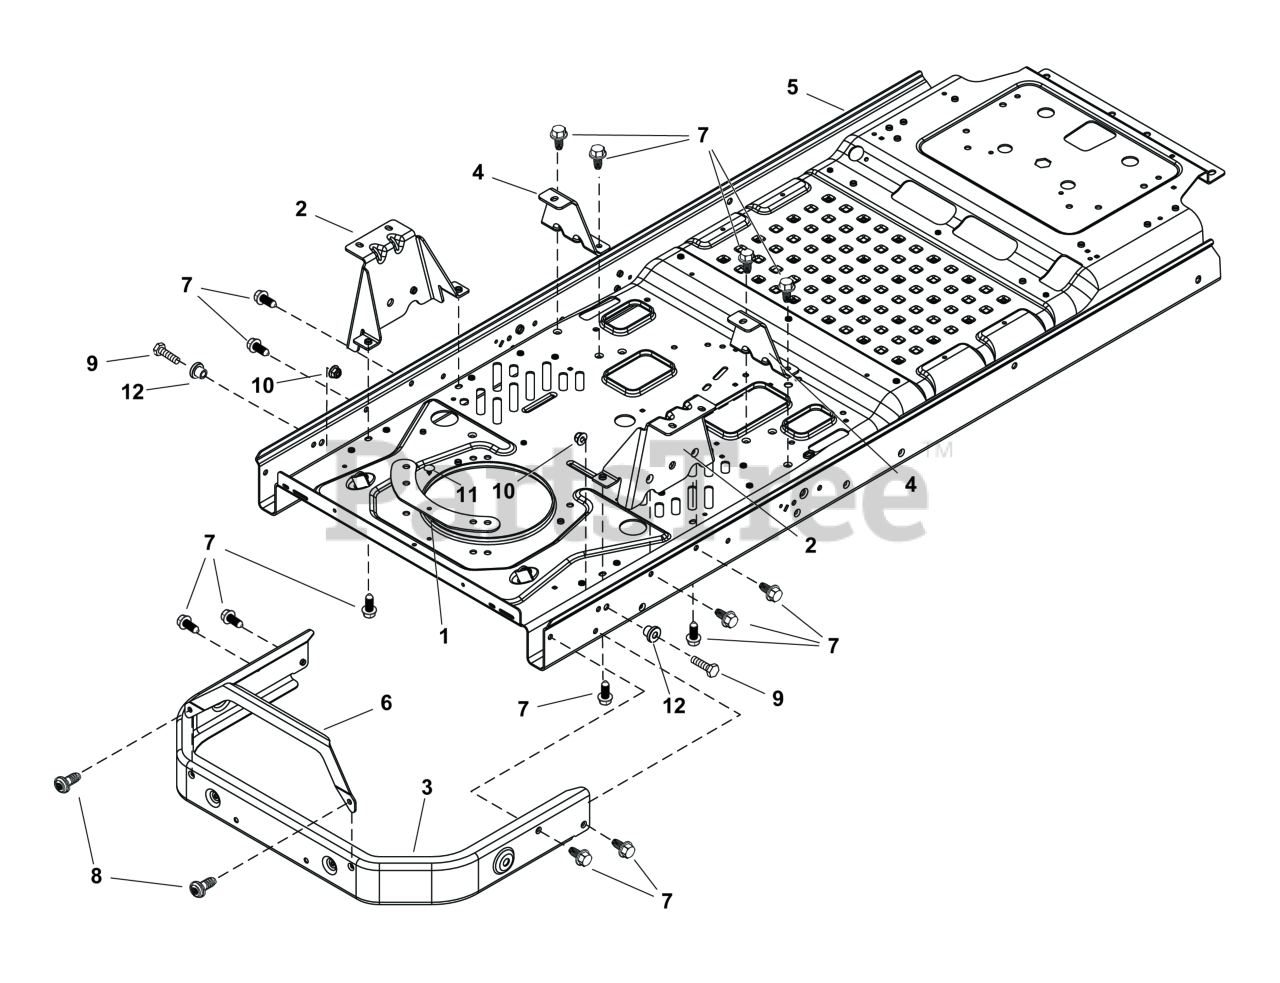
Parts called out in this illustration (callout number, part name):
1	PLATE, Retainer
2	BRACKET, Transmission Mounting (RH)
3	BUMPER, Bumper
4	BRACKET, Transmission Mounting (LH)
6	BRACKET, Rear Muffler Shield
7	SCREW, 5/16-18 X .750, Hex Washer
8	SCREW, 5/16-18, 0.750, Self-Tapping
9	SCREW, 3/8-16 X 1.25, Hex
10	NUT, 3/8-16, Flanged Lock, GR5
11	CLIP, .250 DIA. X .500 LG
12	SPACER, .38 X 1.0 X .70, Shoulder
